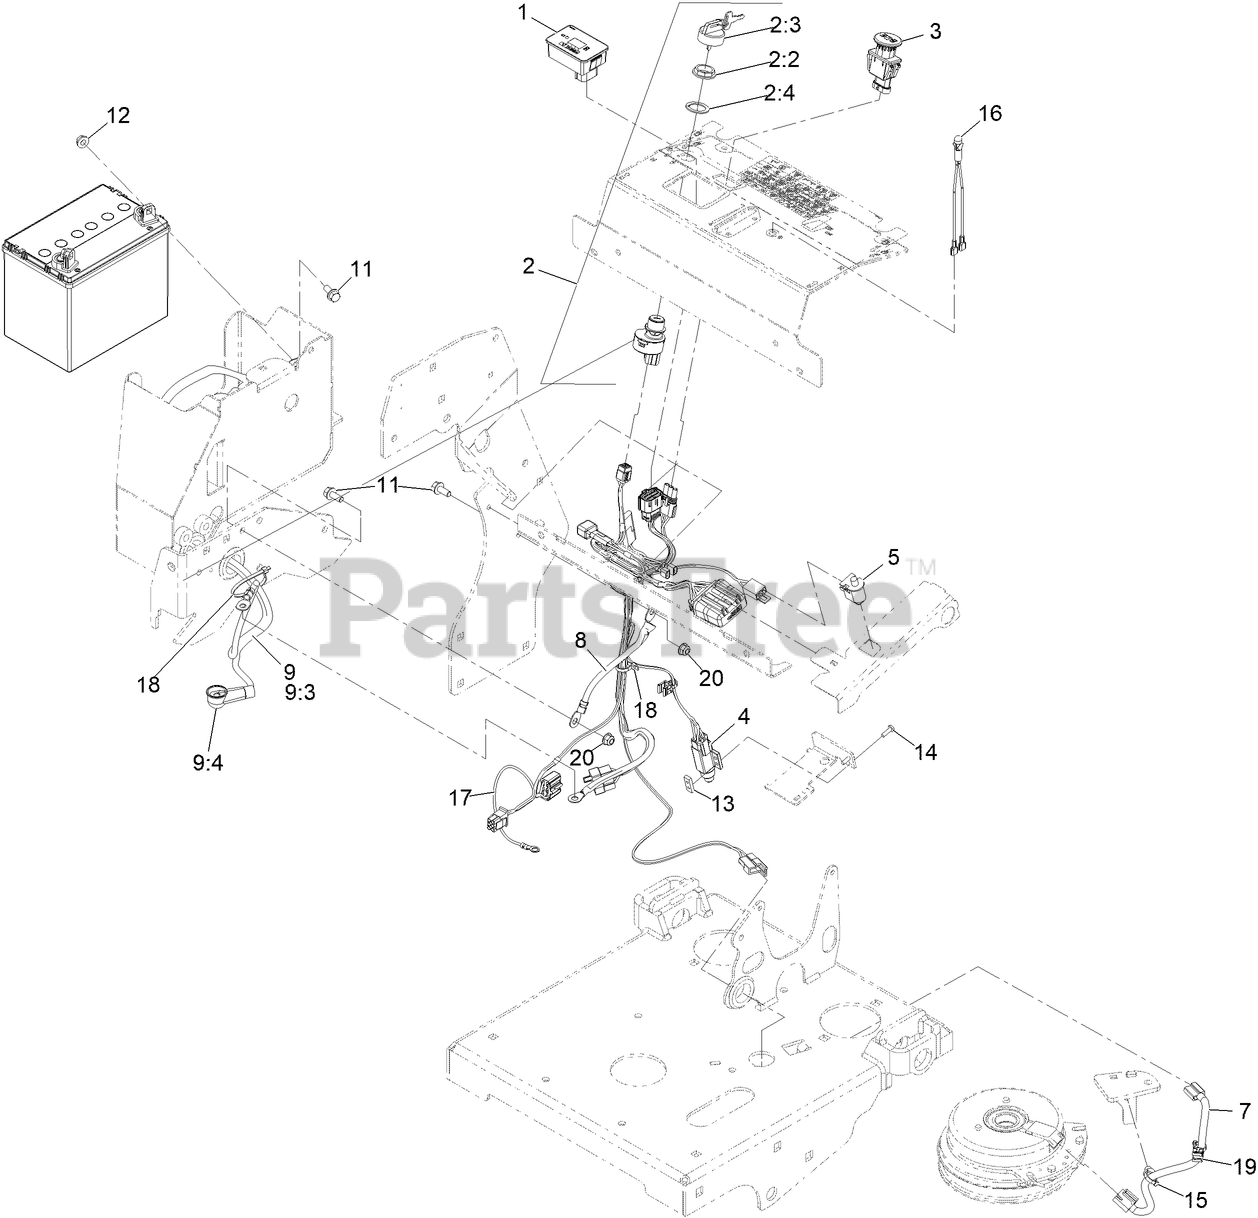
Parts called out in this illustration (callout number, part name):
1	MODULE-HOUR METER
2	IGNITION SWITCH ASM
2:2	NUT-MOUNTING
2:3	IGNITION KEY SET
2:4	WASHER-BACKUP
3	SWITCH-PTO, SEALED
5	SWITCH-BAIL
7	HARNESS-CLUTCH PIGTAIL
8	HARNESS-WIRING
9	HARNESS-BATTERY
9:3	Insulator-Lug, Red
9:4	Boot-Battery, Red
11	SCREW-HHF
13	PLATE-TAPPED
14	SCREW-PPH
15	CLIP-TIE
16	INDICATOR-LED, RED
17	Harness-Indicator Light, EFI
18	TIE-CABLE
19	Clip-Edge
20	NUT-HF, NI
